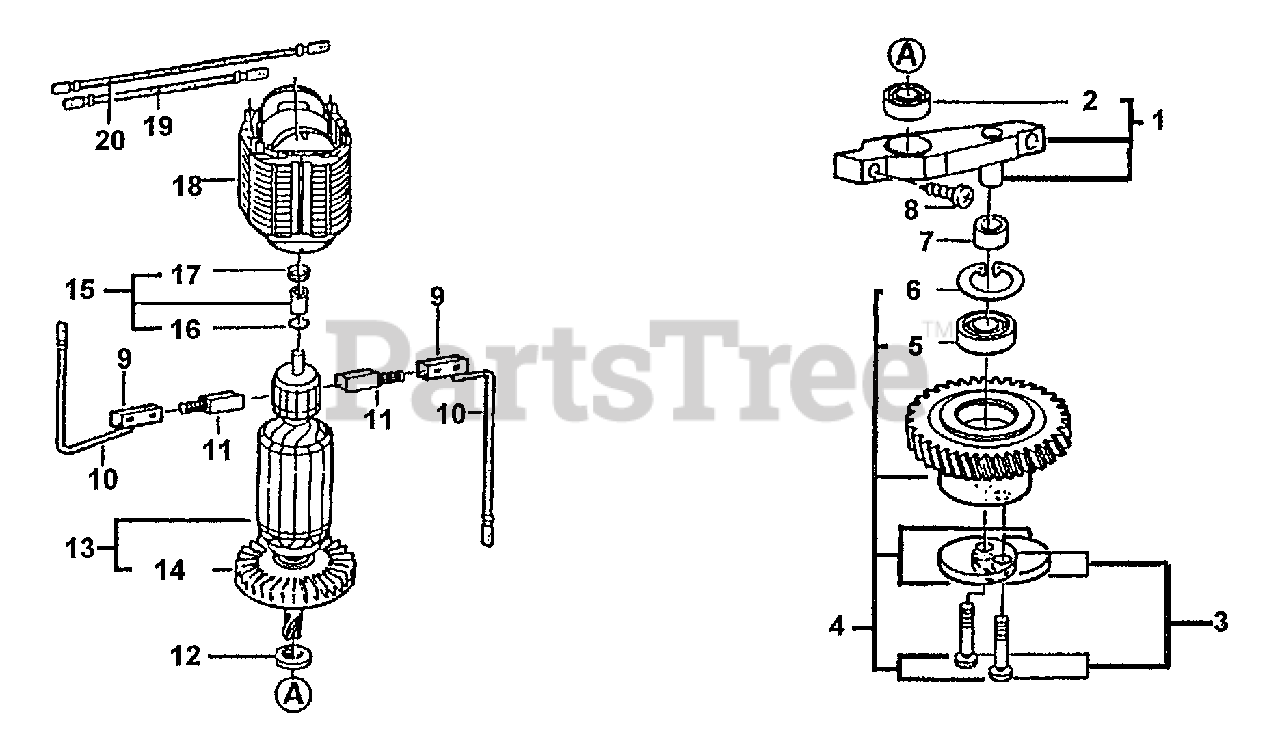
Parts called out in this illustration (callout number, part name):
1	BEARING FLANGE ASSY
2	BEARING, BALL
3	PLATE ASSY
4	GEAR ASSY
5	BEARING, BALL
6	RING, RETAINING
7	SPACER
8	SCREW
9	HOLDER, BRUSH
10	CABLE - 80mm
11	BRUSH SET
13	ARMATURE - 115V
14	FAN
15	BUMPER ASSY
16	O-RING
17	SEAL, FELT
18	FIELD 115V
19	CABLE - 100mm
20	CABLE - 200mm
